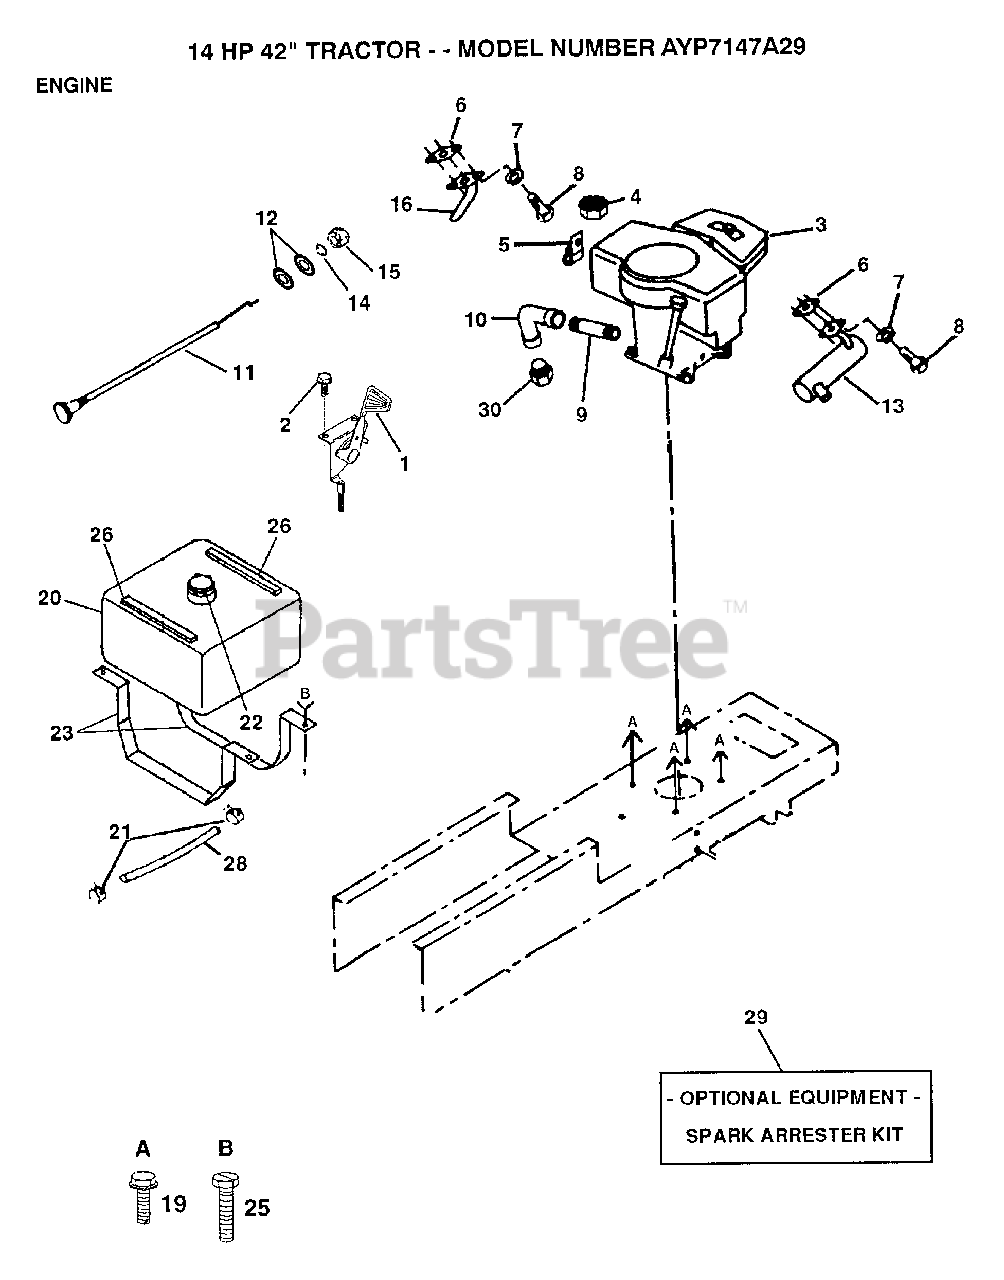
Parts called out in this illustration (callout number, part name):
2	SCREW LT
4	NUT
5	CLIP T
7	LOCKWASHER
9	PIPE NIPPLE LT
10	ELBOW
11	CHOKE CONTROL
12	WASHER
14	LOCKWASHER
16	EXHAUST TUBE T
19	SCREW
21	HOSE CLAMP
23	"STRAP,TANK"
25	SCREW LT
26	"STRIP,FORM"
28	HOSE T
